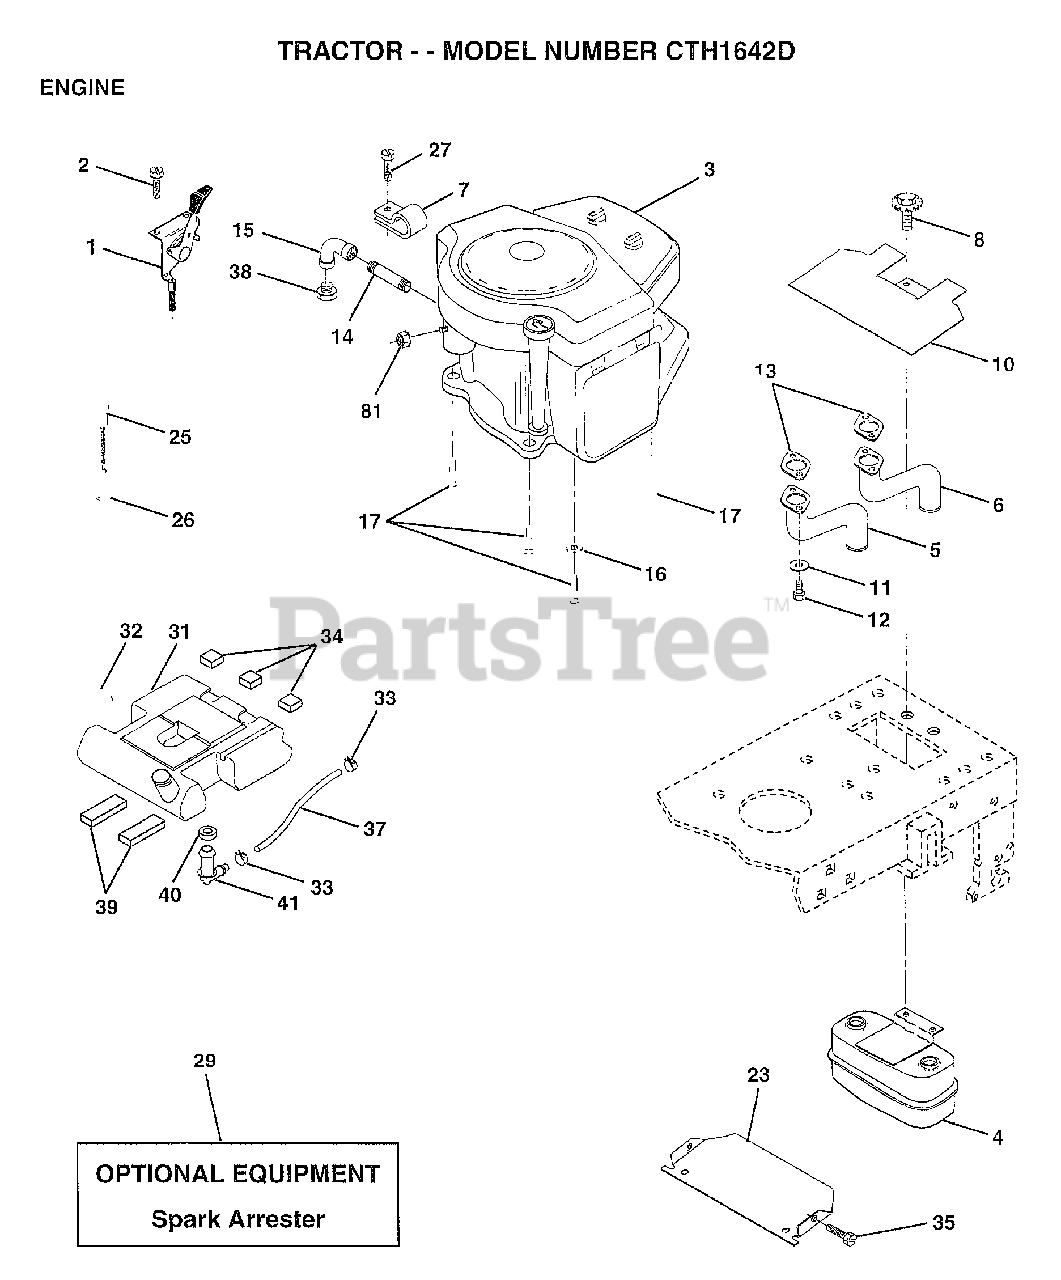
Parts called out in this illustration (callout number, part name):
2	SCREW LT
4	MUFFLER.TW.LOTONE
5	EXHAUST.B&S.18.LH
6	EXHAUST.B&S.18.RH
7	CLAMP.TUBE.DBL.EN
8	BOLT.5/16-18.UNC
10	SHIELD.HEAT.
11	LOCKWASHER
13	GASKET MUFFLER
14	PIPE NIPPLE LT
15	ELBOW
16	LOCKWASHER
17	SCREW LT
23	SHIELD-HEAT
25	"CONTROL.CHOKE.51"""
26	"NUT,KEPS 3/8-24IM"
27	"SCREW-TT,10-32 FL"
31	TANK FUEL REAR
32	CAP ASM FUEL
33	HOSE CLAMP
34	PAD-SPACER LT
35	SCREW
37	FUEL LINE T
39	PAD IDLER TI
40	BUSHING OUTLET T
41	STEM.TANK.FUEL
81	NUT
